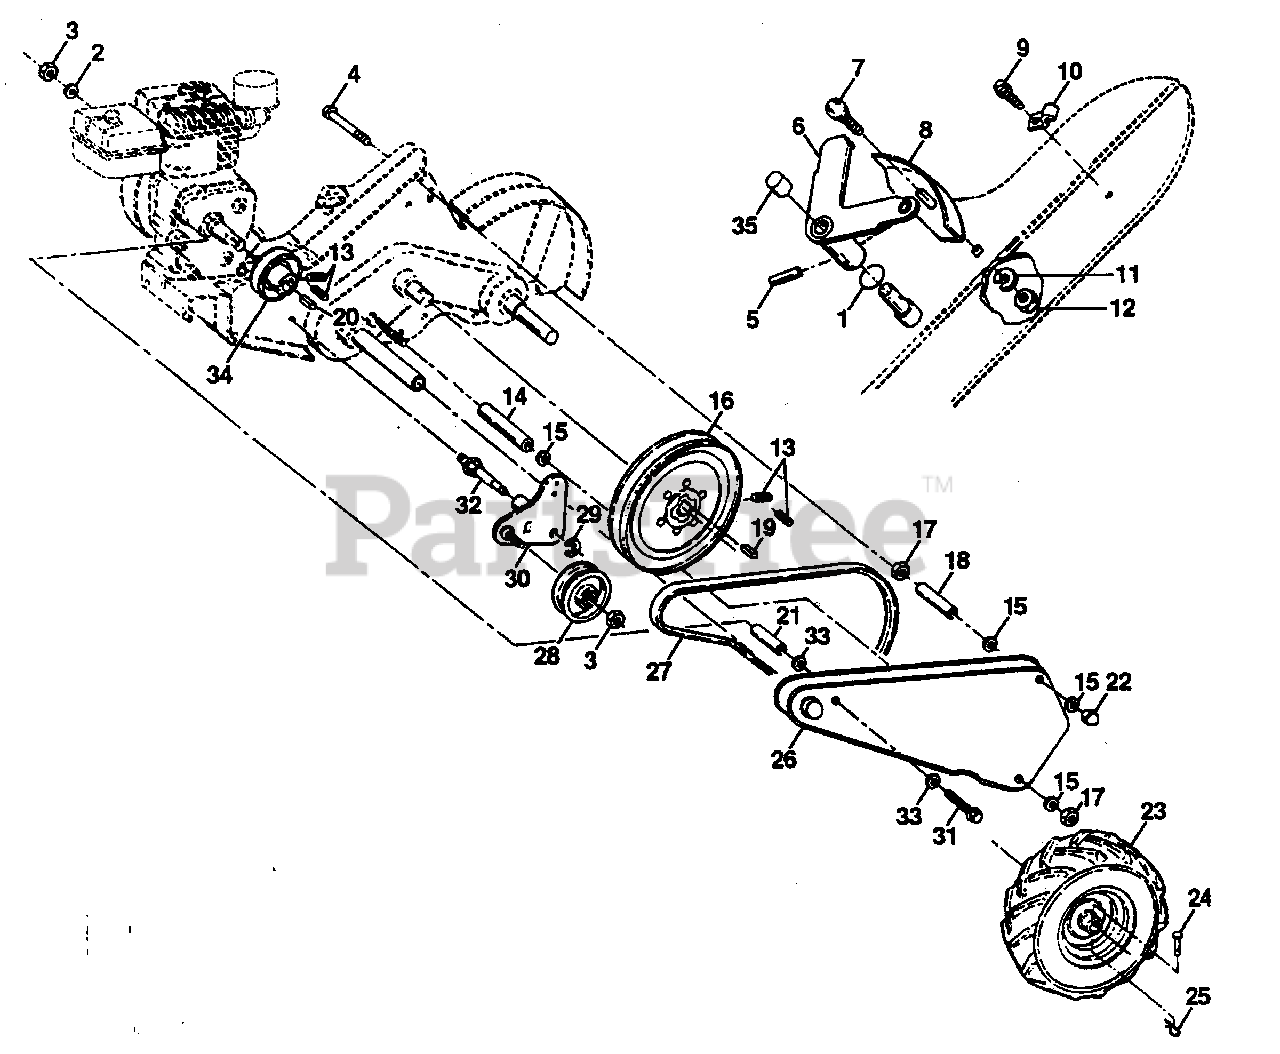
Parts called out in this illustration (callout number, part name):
2	Washer, Lock 3/8
3	Nut, Hex 3/8-16
4	Bolt, Hex Head 5/16-18 x 4-1/2
5	Pin, Roll
7	Bolt, Carriage 1/4-20 x 1/2 Grade 5
8	Plate, Shift Indicator
9	Screw, Hex Washer Head, Slotted #10-24 x 1/2
11	Washer, Lock 1/4
12	Nut, Hex 1/4-20
13	Screw, Set, Hex 5/16-18 x 3/8
14	Spacer, Split
15	Washer 11/32 x 11/16 x 16 Gauge
16	Sheave, Transmission
17	Nut, Hex 5/16-18
19	Key, Square 3/16 x 1-1/8
21	Spacer, Split .523 x .718 x 2
22	Nut, Cap 5/16-18
24	Rivet, Drilled
25	Clip, Hairpin
28	Pulley, Idler
30	Bracket, Idler
31	Bolt, Hex Head 1/2-20 x 2-3/4
32	Shaft, Idler Arm
33	Washer
34	Sheave, Engine
